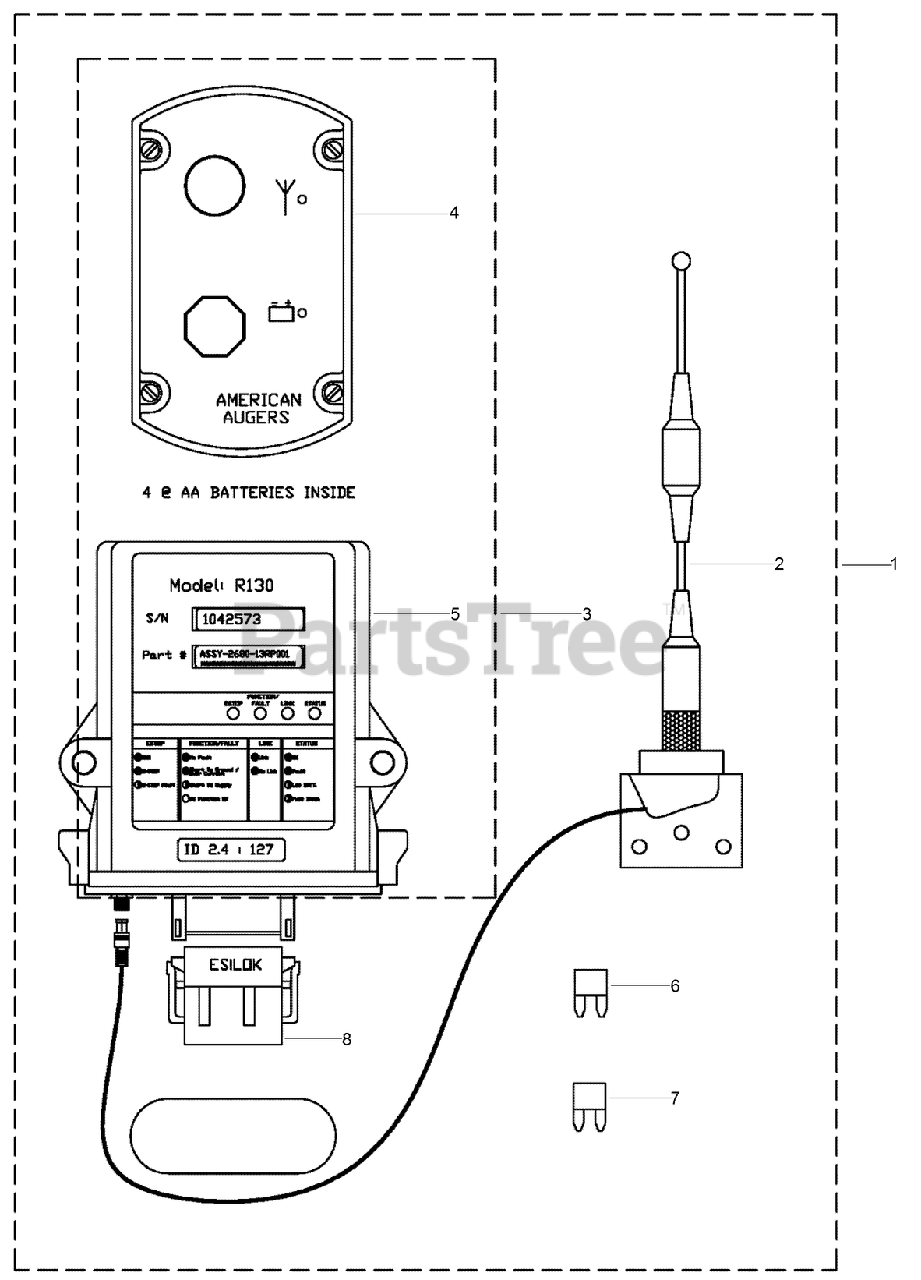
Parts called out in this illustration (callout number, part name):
1	LOCKOUT - Exit Side
2	ANTENNA
3	EXIT SIDE LOCKOUT - T50+R130
4	TRANSMITTER
5	RECEIVER
6	FUSE - 7.5 Amp
7	FUSE - 10 Amp
8	PLUG - Female, 12 Socket
